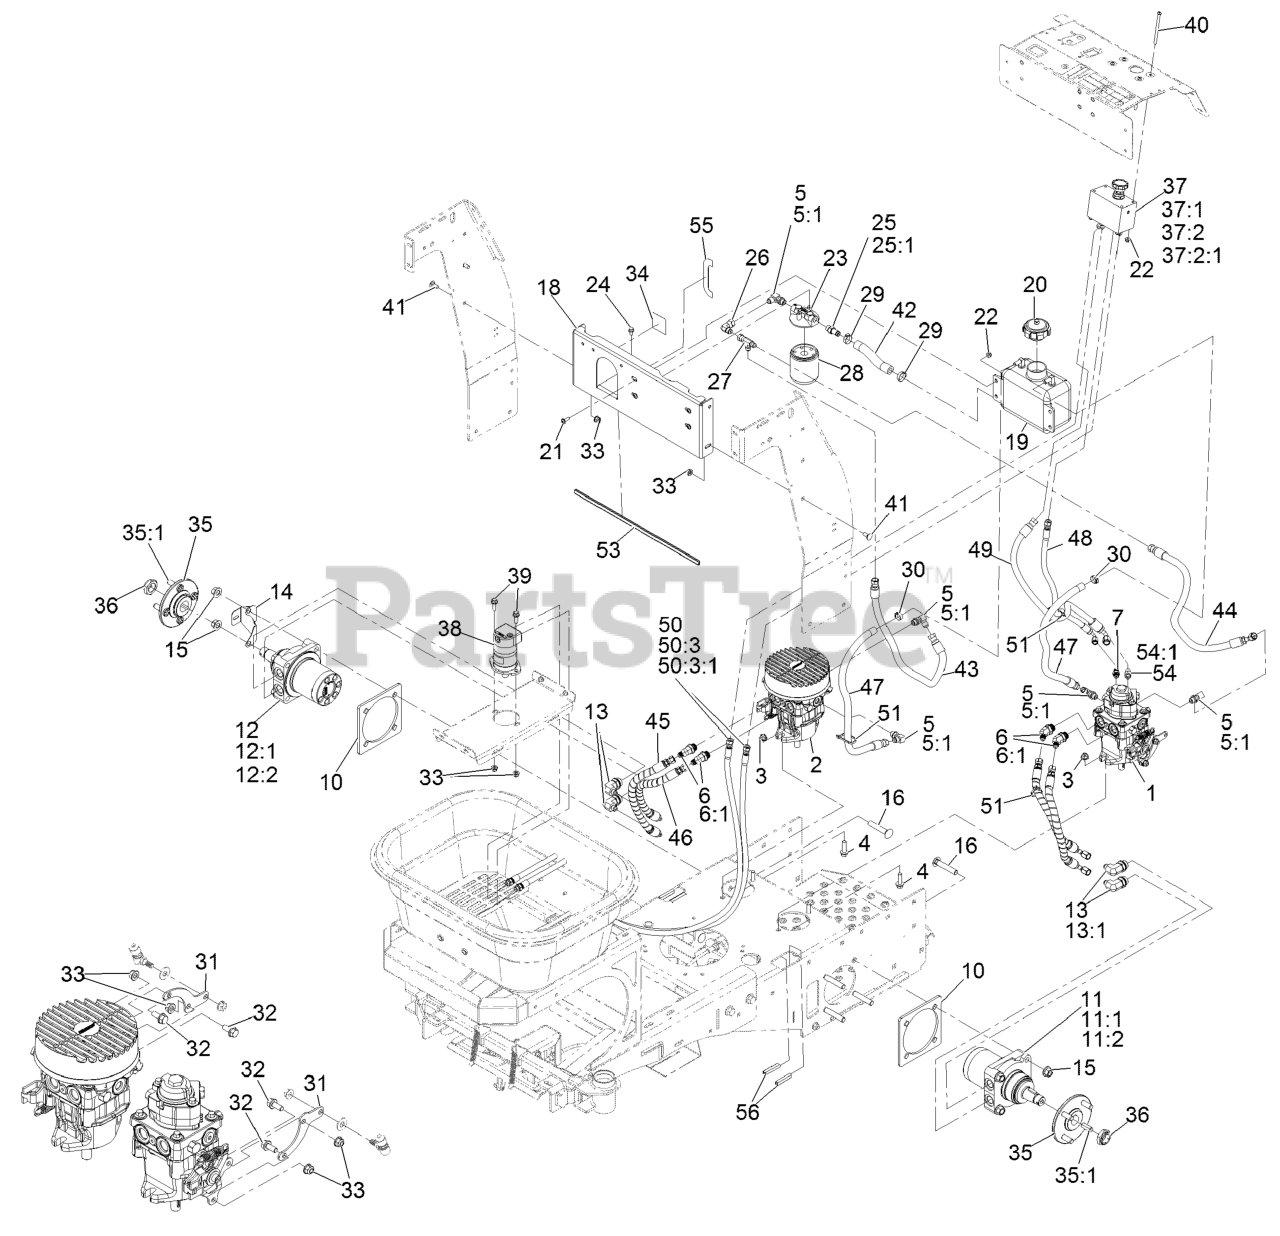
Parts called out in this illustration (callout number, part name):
1	PUMP-HYDRO, PG WITH AUX
2	PUMP-HYDRO, PG
3	Nut-Hex Flange
4	SCREW-HHF
5	FITTING-ELBOW, 90 DEG
5:1	O-RING
6	FITTING
6:1	O-RING
7	FITTING-STRAIGHT
10	BACKPLATE, WHEEL, JR36
11	MOTOR-WHEEL,LT
11:1	KEY-WOODRUFF
11:2	KIT-SEAL, TJ MOTOR
12	MOTOR-WHEEL,RT
12:1	KEY-WOODRUFF
12:2	KIT-SEAL, TJ MOTOR
13	FITTING-ELBOW, 90 DEG
13:1	O-RING
14	BRACKET-HOPPER, SPEEDOMET
15	Nut-Lock 1/2-13
16	SCREW-CARR
18	MOUNT, HYDRAULIC FILTER,
19	2 QT FLAMBEAU HYDRO TANK
20	Cap-Vented
21	Screw-Hsbhf
22	Nut-Hex Flange
23	HEAD-FILTER
24	SCREW-HHF
25	ADAPTER-STRAIGHT
25:1	O-RING
26	ELBOW-SWIVEL, 90 DEG
27	FITTING-HYD, TEE
28	FILTER-25 MICRON, BI-DIRECTIONAL
29	CLAMP-OETIKER, 167
30	CLAMP-OETIKER, 167
31	EXTENSION, HYDRO-PUMP, JR
32	SCREW-HHF
33	Nut-Hex Flange
34	DECAL-OIL
35	HUB-WHEEL
35:1	STUD-1/2-20 X 1.55
36	LOCKNUT
37	Manifold-Flow Control, Hopper
37:2	FITTING-ELBOW, 45 DEG
37:2:1	O-RING
38	MOTOR-HYDRAULIC, SPREADER
39	SCREW-HHF
40	Screw-HSBH
41	SCREW-CARR
42	HOSE-HYDRAULIC
43	HOSE ASM, HYD LP
44	HOSE ASM, HYD LP
45	HOSE ASM-HYD HP
46	HOSE ASM-HYD HP
47	HOSE ASM, HYD LP
48	Hose ASM-HYD HP
49	HOSE ASM, HYD LP
50	Hose ASM-HYD HP
50:3	Fitting-Straight, Rigid
50:3:1	O-RING
51	TIE-CABLE
53	STRIP-TRIM, 17.88""
54	Adapter-Straight
54:1	O-RING
55	DECAL-HYDRO LEVEL
56	STRIP-TRIM, 2.0""
